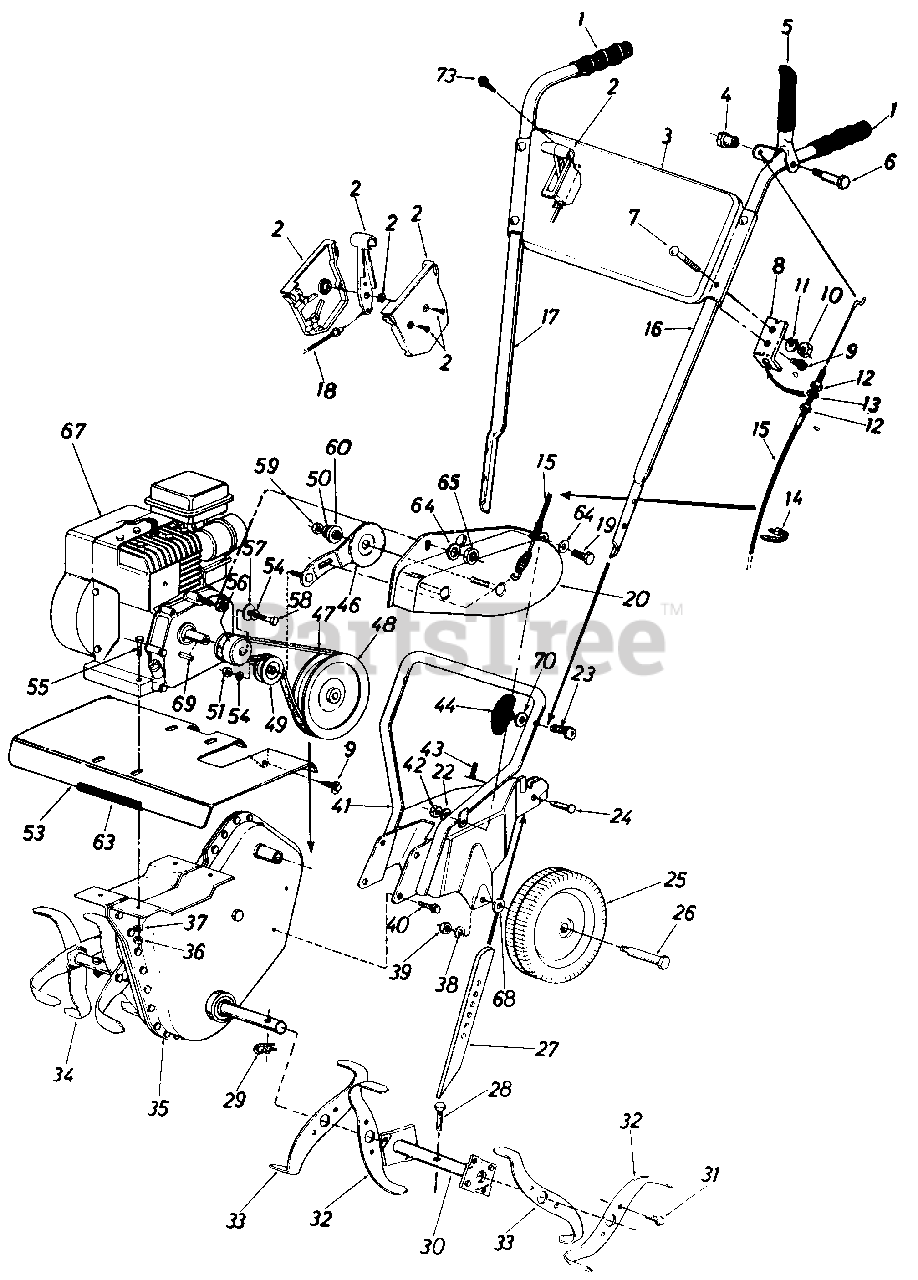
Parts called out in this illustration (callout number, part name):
2	Throttle Control Box Ass'y.
3	Handle Panel
4	Shoulder Nut
5	Clutch Grip Ass'y.
6	Shoulder Bolt 3/8" x 1.16"
7	Carriage Bolt 5/16-18 x 1.5" Lg.
8	Cable Support Bracket
9	Hex Wash. Hd. Self-Tap Scr. 1/4-20 x .50" Lg.
10	Hex Nut 5/16-18 Thd.
11	L-Wash. 5/16" l.D.
12	Hex Jam Nut 5/16-24 Thd.
13	L-Wash. 5/16" l.D.
14	Cable Tie
15	Clutch Control Cable
19	Hex Bolt 1/4-20 x .75" Lg.
20	Belt Cover Ass'y.
22	L-Wash. 1/4" l.D.
23	Curved Hd. Bolt 5/16-18 x 1.75" Lg.
24	Clevis Pin
25	Wheel Ass'y. Comp.-Plastic
25	Wheel Ass'y. Comp.-Steel
25	Wheel Bearings
26	Shoulder Bolt
29	Hairpin Cotter
30	Tine Adapter Ass'y.
31	Hex Wash. Hd. Self-Tap Scr. l/4-20 x .6" Lg.
32	Tine Blade L.H.
33	Tine Blade-R.H.
34	Tine Ass'y. Comp.
35	483Chain Case Ass'y. Comp.
36	Hex Nut 5/16-18 Thd.
37	L-Wash. 5/16" I.D.
38	L-Wash. 3/8" l.D. (Heavy Duty)
39	Hex Cent. L-Nut 3/8-16 Thd.
40	Hex Wash. Hd. Self-Tap Scr. 5/16-1 8 x .50" Lg.
43	Internal Cotter Pin
44	Hand Knob
46	Idler Amm Ass'y.
48	Chain Case Pulley 6-l/2" x 1/2"
49	Fl-ldler 2"
50	L-Wash. 5/16" l.D.
51	Hex Nut 3/8-24 Thd.
55	Hex Bolt 5/16-18 x 1.5" Lg.
56	Engine Pulley 3/8" V
57	Fl-Wash. .385 I.D. x 1" O.D.
58	Hex Bolt 3/8-24 x 1" Lg.
59	Hex Nut 5/16-18 Thd.
60	Shld. Spacer .50" Dia.
63	Trim Strip 4-1/2"
64	Fl-Wash. .281" I.D. x .5" O.D.
65	Hex Cent. L-Nut 1/4-20 Thd.
67	Engine
68	Bell-Wash.
69	Square Key 3/16" x 3/4" Lg.
70	Bell-Wash.
73	Self-Tap Screw #10 x .5" Lg.
